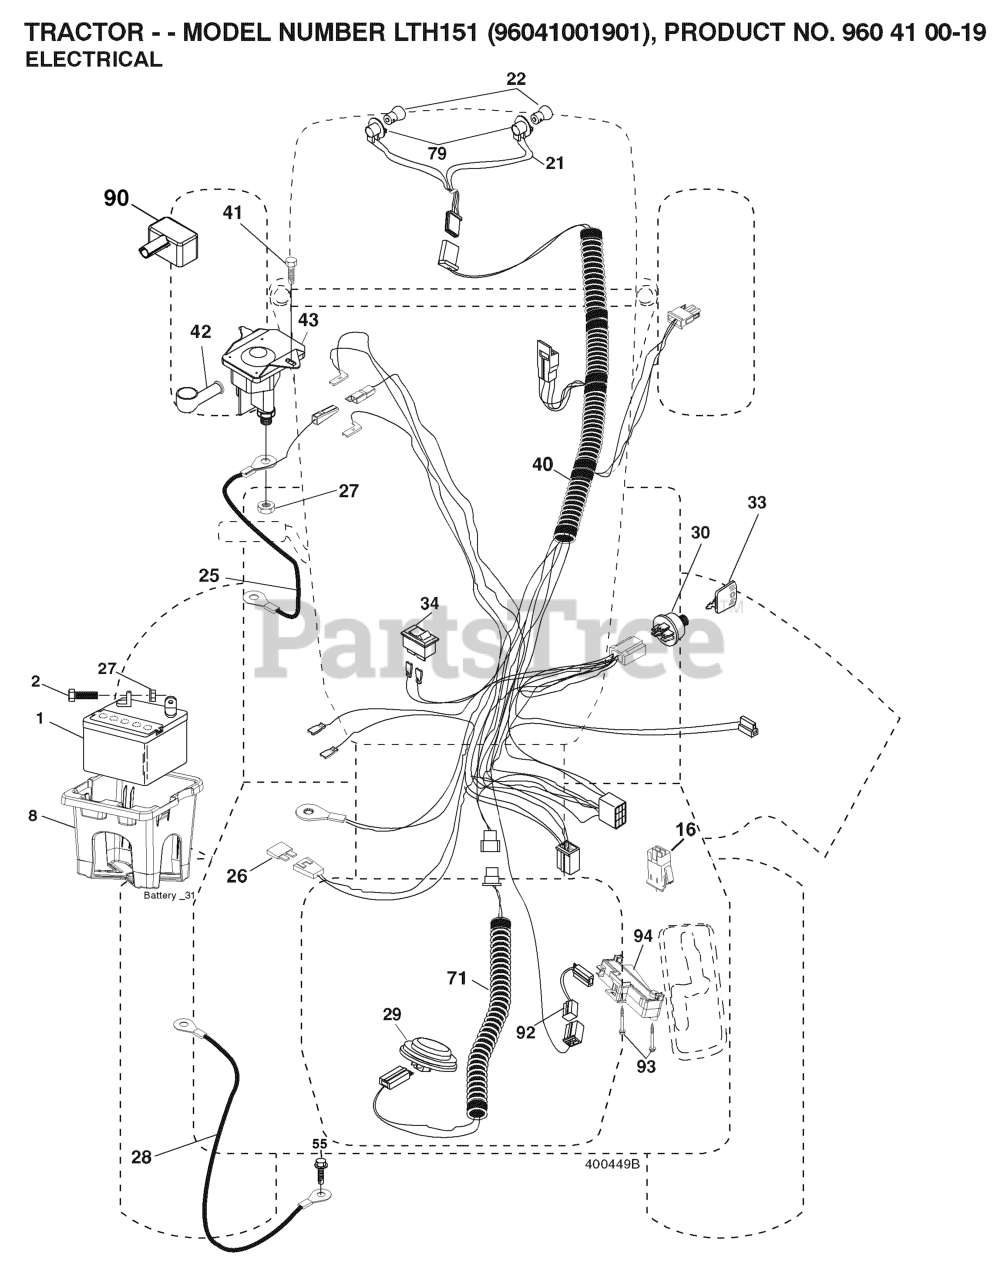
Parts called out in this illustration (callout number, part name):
1	BATTERY 12V .35 AMP
2	BOLT.HEX.1/4.X.3/4.DICHROMATE
8	BOX.BATTERY.MNT.REAR.L
16	SWITCH INTERLOOK PUSH-IN
21	HARNESS.LIGHT W/4152J BULBS
25	CABLE.STARTER.6GA.RED.
26	FUSE 20AMP
27	NUT
28	CABLE.BLACK.18"REAR.BA
29	SWITCH.SEAT.DELTA.OPC.
30	SWITCH.IGN.DELTA.W.LGH.ROS
33	KEY MLD GEN DELTA
40	HARNESS IGN. DASH
41	SCREW
42	TERMINAL COVER
43	SOLENOID.W/BRASS.PLUNGER
55	SCREW 5/16"
71	HARNESS.IGN.CHASS.TEX.REAR.BAT
79	BULB HOLDER ASM.
90	COVER, TERMINAL BATTERY
92	HARNESS.PIGTAIL.CONSLE
93	SCREW.PLASTITE
94	MODULE.REVERSE.ROS
